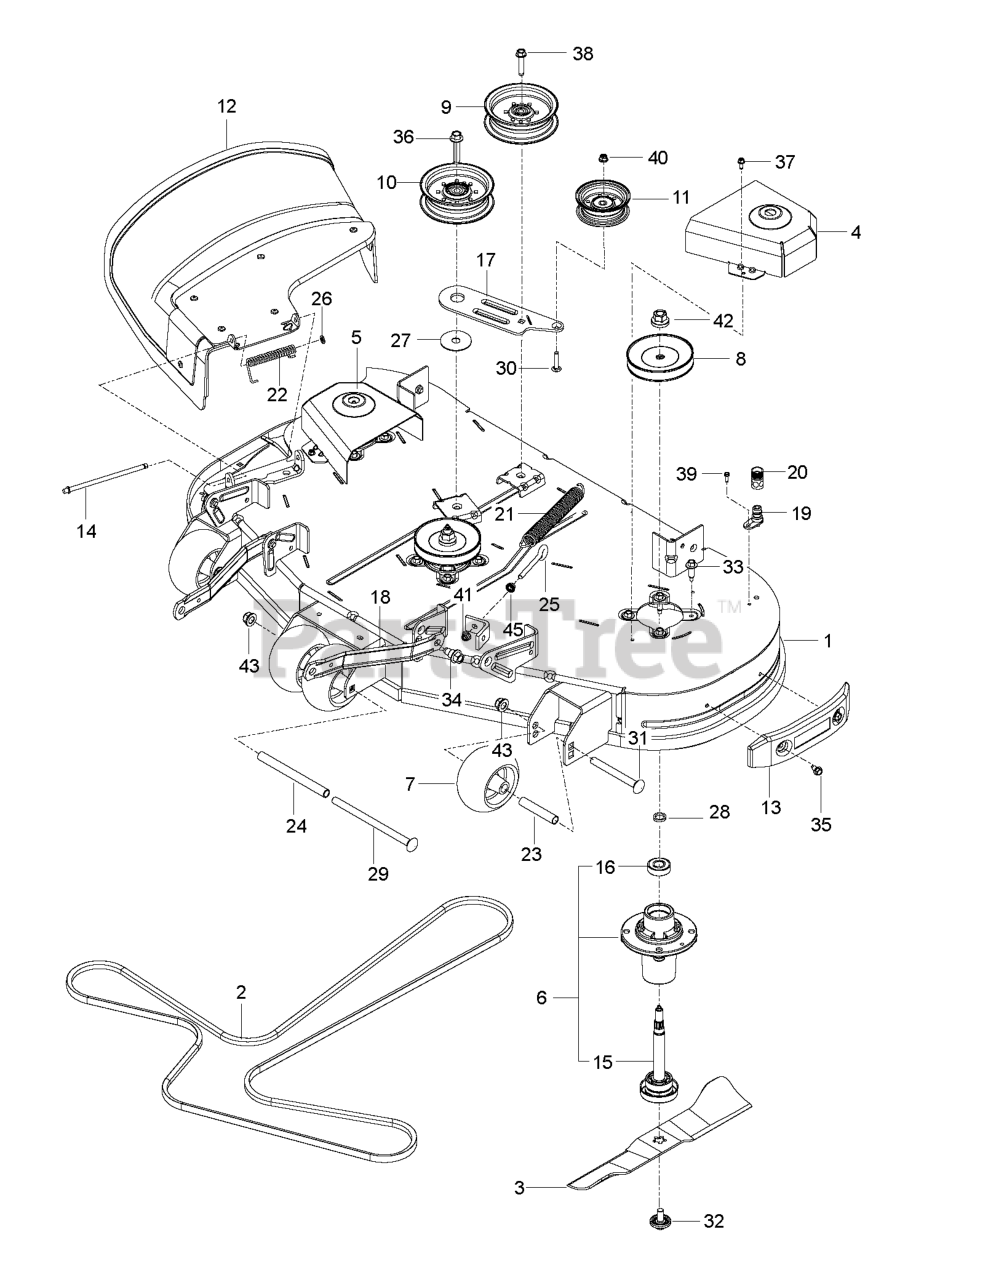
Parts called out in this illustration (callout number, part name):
1	DECK.SVC.48.CC.MZ.668
2	BELT.DRIVE
3	BLADE.BAGGER.RES.CLRCT.48".BLK
4	COVER.PNT.MANDREL.LH.ZTR.GREY
5	COVER.PNT.MANDREL.RH.GREY
6	MANDREL ASM, CAST IRON
6	MANDREL.DECK.ASSEMBLY
7	ROLLER, GAUGE .635 BORN
8	MANDREL.PULLEY.38.BRIGHT.ZINC
9	PULLEY.IDLER.2006
10	PULLEY.IDLER.MWR.STATI.LH
11	PULLEY.IDLER.48"PRIMARY
12	DEFLECTOR.ASM.48".CLRCT.RES.OR
13	BUMPER.ASM.SIDE.TRIM.CLRCUT.48
14	ROD.HINGE
15	SHAFT ASM MANDREL
17	ARM.PNT.CLUTCHING.EDIP
18	ARM.SUSPENSION.MOWER
19	PORT.WASHOUT
20	COUPLING.QUICK CONNECT
21	SPRING.EXTENSION
22	SPRING.42.FCS.DEFLECTOR
23	TUBE, ROLLER AXLE LONG
24	TUBE, ROLLER AXLE
25	EYE BOLT 5/16 X 3.50
26	NUT PUSH M
28	WASHER.SPACER.MANDREL
29	RHSNB 1/2-13 X 8 GR5 ZD
31	RHSNB 1/2-13 X 4.75 GR5 ZD
32	BOLT.WASHER.ASM.7/16-2
33	BOLT.HEX.WASHR.HED.313-18X1.19
34	BOLT.SHOULDER
35	BOLT.5/16HEX.WHS.HD
36	SCREW.7/16-14 X 2.125.WASHER
37	SCREW.1/4-20X5/8
38	SCREW LT
39	SCREW
40	NUT LOCK FLG 3/8-16 UNC
41	5/16-18 NYLOC FLANGE NUT
42	NUT.FLANGE.LOCK.TOP
43	NUT, 1/2-13 HEX FLG NYLOC ZD
45	NUT 5/16C WHIZ
